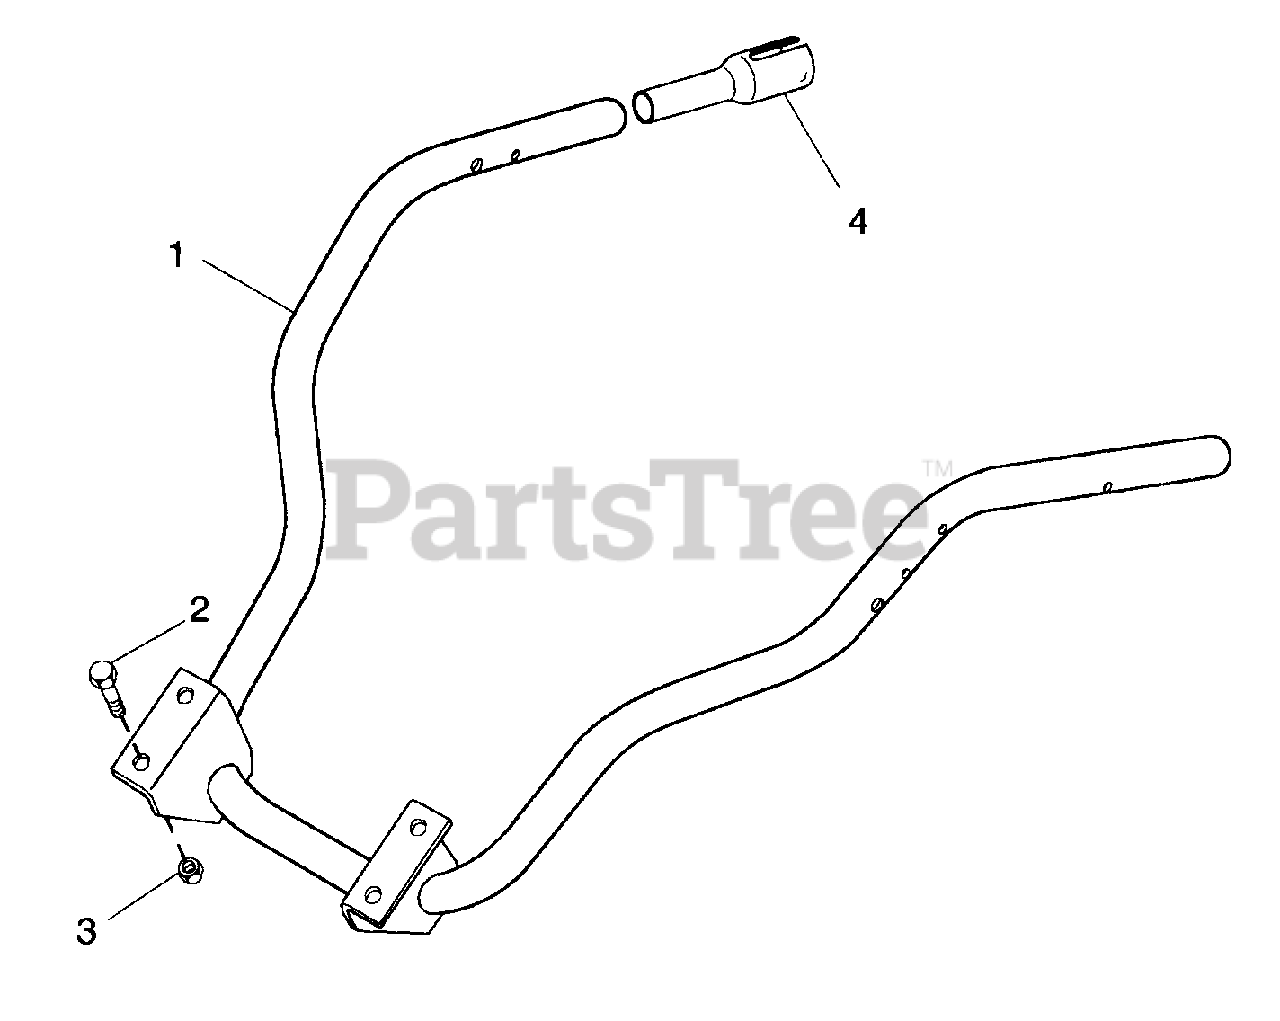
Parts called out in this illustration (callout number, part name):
1	Weldment, Handlebar
2	Bolt-Hex .38-16 x 1.25 Grade 8
3	Nut-Locking-Nylon .375-16
4	Insert, Handlebar
